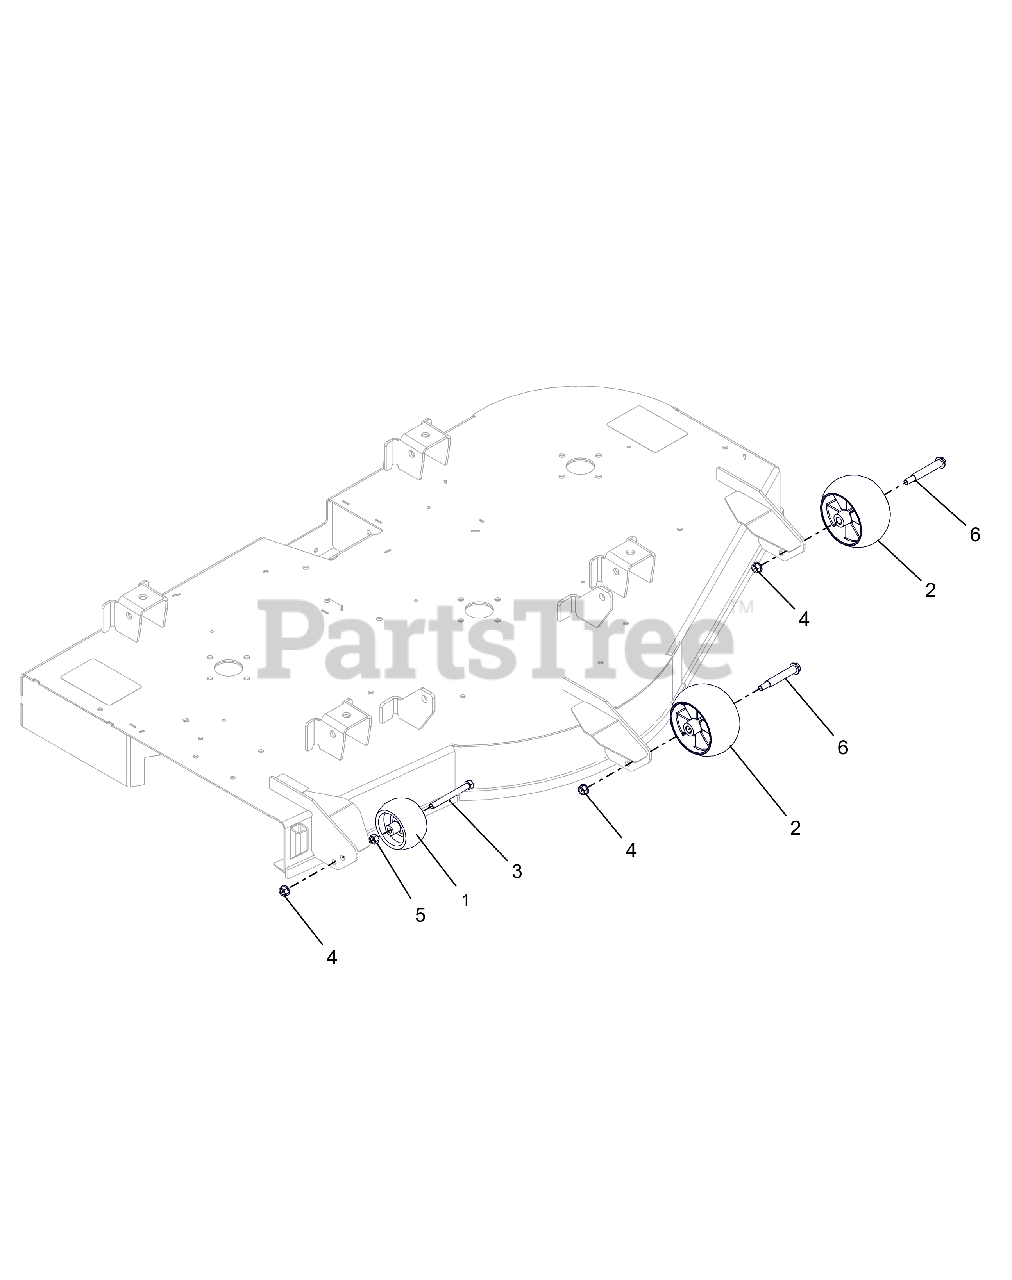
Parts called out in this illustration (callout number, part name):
2	ANTI-SCALP WHEEL - 5X OS
3	BLT, HEX .38-16X3.50 G5 ZCC
4	NUT-LK-TOP-FLG .38-16 ZC120
5	NUT-STD .375-16 G2 ZCC
6	BLT-SHLDR .38-16X2.50 HWH G5
